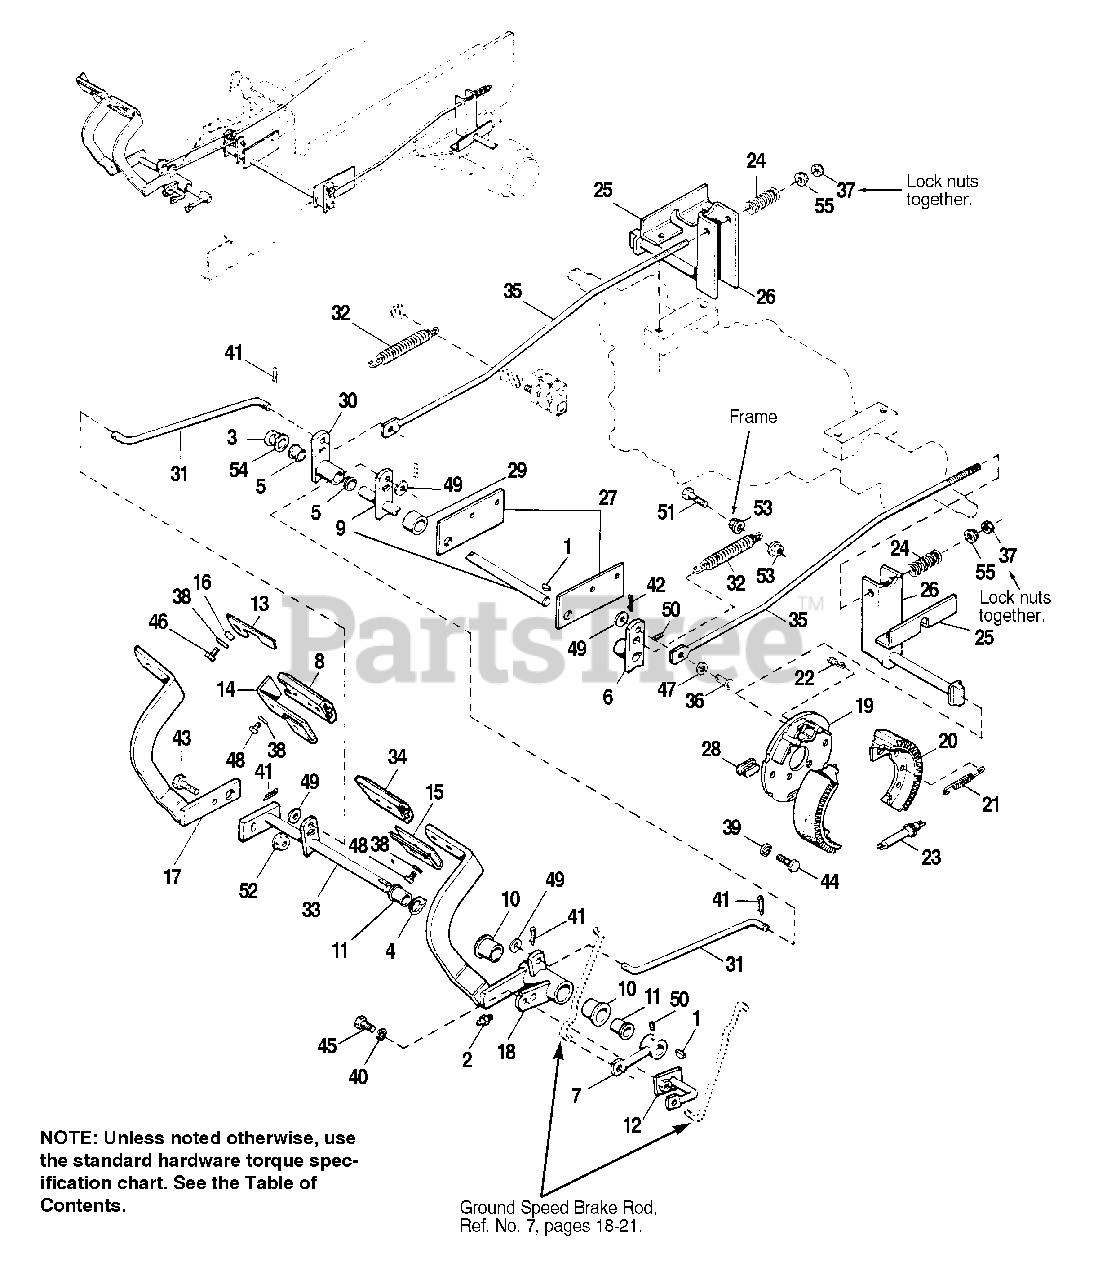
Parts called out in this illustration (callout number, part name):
1	KEY, Woodruff #9
2	FITTING, Lube, 1/4" Drive
3	RING, Retaining
4	RING, Retaining
6	LEVER ASSY., Brake
7	ROD ASSY., Pivot Plate
9	SHAFT & LEVER ASSY., Brake Pivot
10	BUSHING, 1-1/4 x 1-3/4 x 1
11	BUSHING, 3/4 x 7/8 x 1
12	ROD ASSY., Lock
13	LOCK, Pedal
14	SUPPORT, Pedal Lock
15	SUPPORT, Lock
17	LEVER ASSY., Brake, RH
18	LEVER ASSY., Brake, LH
19	BRAKE SUPPORT ASSY.
20	BRAKE SHOE & PAD ASSY.
21	SPRING, Extension
22	SPRING, Extension
23	SCREW ASSY., Brake Adjusting
24	SPRING, Compression
25	SUPPORT, Actuator
26	ACTUATOR ASSY.
27	SUPPORT, Brake Cross Shaft
29	SPACER
30	LEVER ASSY., Brake
31	ROD & PLATE, Brake
32	SPRING, Extension
33	SHAFT ASSY., Brake, RH
34	PAD, Pedal, Inner
35	ROD ASSY.
37	NUT, Hex, 1/2-13
38	LOCKWASHER, 1/4
39	LOCKWASHER, 3/8
40	LOCKWASHER, 5/16
41	PIN, Cotter, 1/8-3/4
42	PIN, Cotter, 1/8 x 3/4
43	CAPSCREW, Hex Hd., 7/16-14 x 1-1/4
44	CAPSCREW, Hex Hd., 3/8-16 x 1
45	CAPSCREW, Hex Hd.
46	CAPSCREW, Hex Hd., 1/4-20 x 1
47	WASHER, 13/32
48	CAPSCREW, Hex Hd., 1/4-20 x 3/4
49	WASHER, Plain, 13/32 x 7/8 x 5/64
50	SETSCREW, Sq. Hd., 5/16-18 x 1/2
51	CAPSCREW, Hex, 5/16-18 x 1-1/4
52	LOCKNUT, Hex, Whiz, 7/16-14
53	NUT, Hex, Flange Lock, 5/16-18
54	WASHER, Plain, 3/4
55	NUT, Large Flange, 1/2-13
